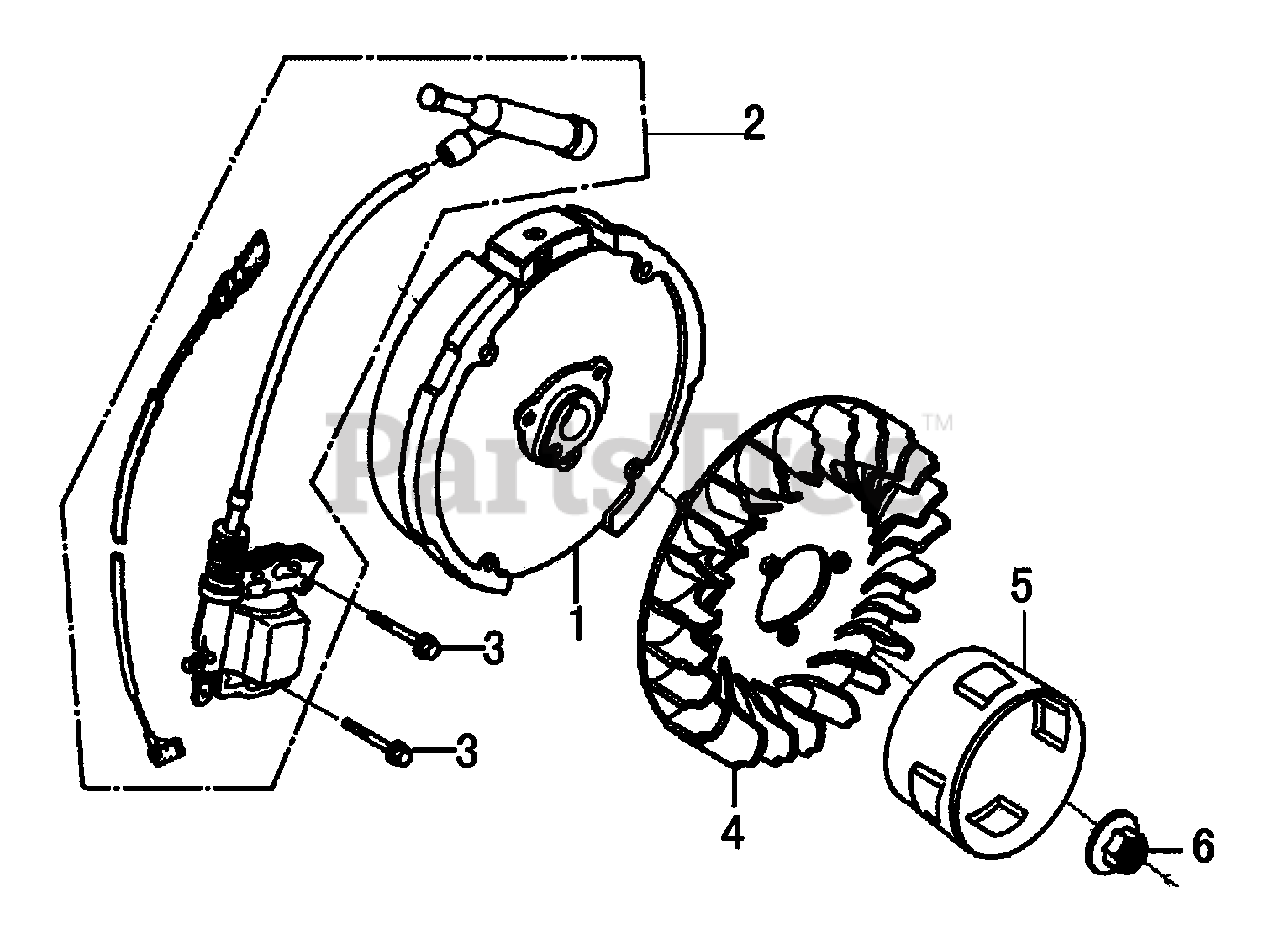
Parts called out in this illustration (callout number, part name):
1	FLYWHEEL COMP
2	COIL ASSY., IGNITION
3	BOLT, FLANGE
4	FAN, COOLING
5	PULLEY, STARTER
6	NUT, SPECIAL
